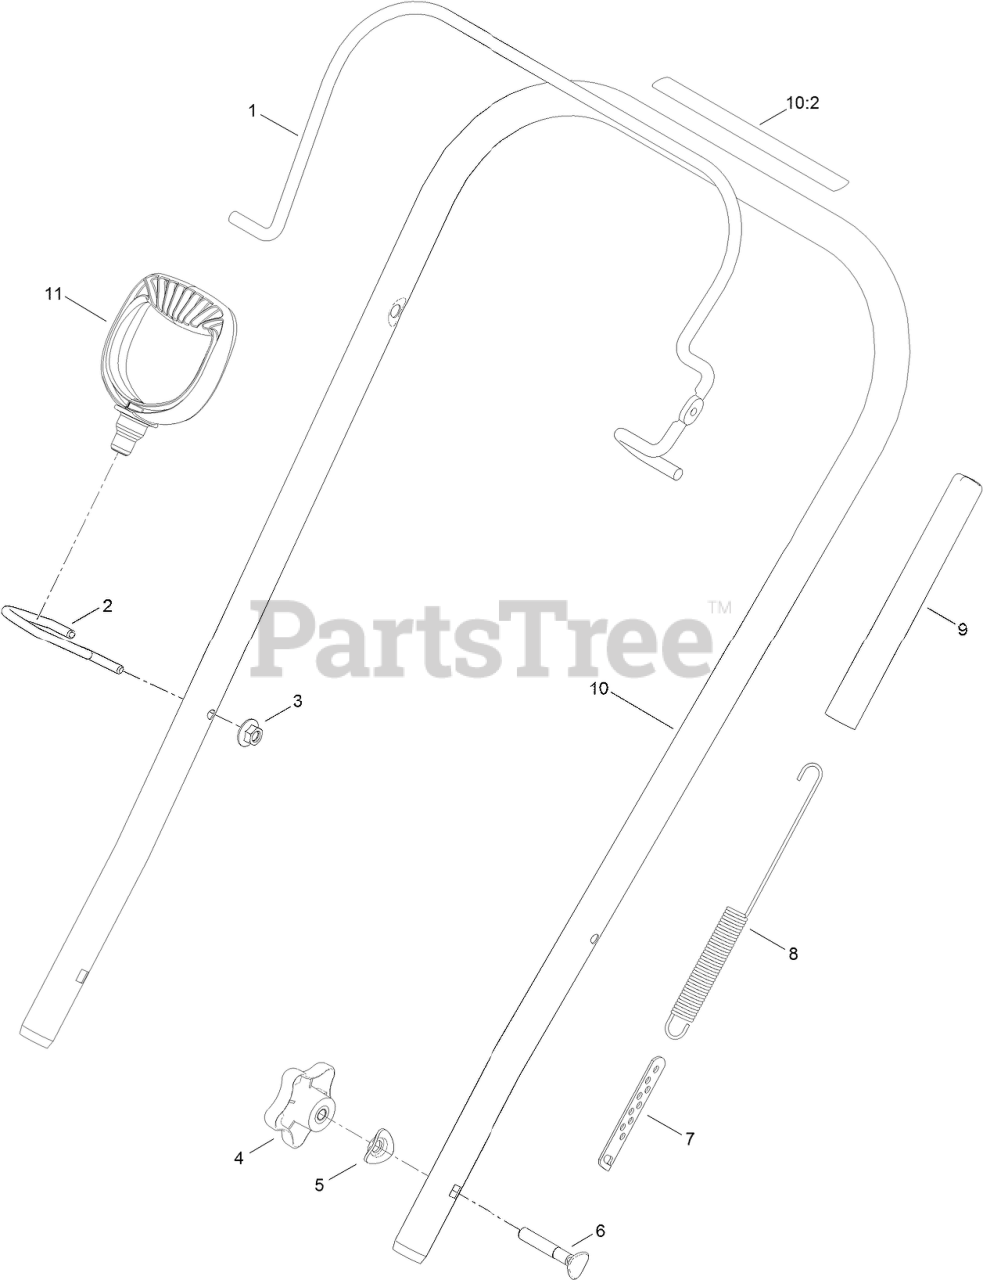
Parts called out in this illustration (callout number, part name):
1	BAIL-CLUTCH
2	GUIDE-ROPE
3	NUT-HEX FLG
4	KNOB-HANDLE
5	WASHER
6	SCREW-HANDLE
7	ADJUSTER-CABLE, CLUTCH
8	SPRING-CLUTCH
9	COVER-SPRING
10	UPPER HANDLE ASM
10:2	DECAL-SAFETY
11	HANDLE-RECOIL
